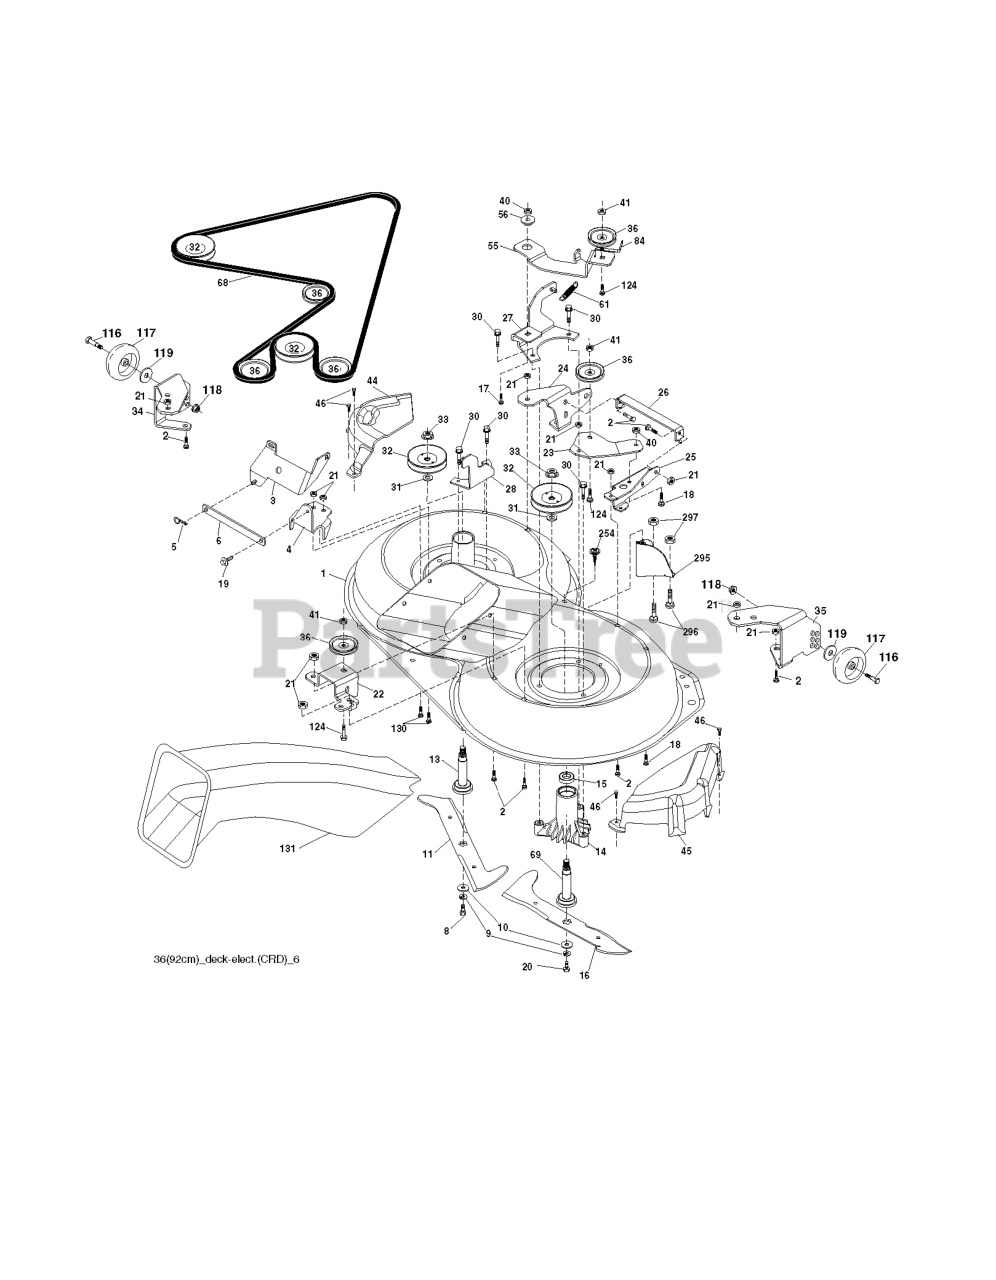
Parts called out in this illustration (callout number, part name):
2	RP BOLT 5/16-18 X3/4 ZN/YEL GR
5	RETAINER-SPRNG RB
6	BAR.SWAY.92.CRD
8	BOLT.3/8-24X1.25 GR8
9	LOCKWASHER
10	WASHER.BLADE
13	SHAFT ASM VENT
14	HOUSING.MANDREL.VENTED (MACHD)
17	BOLT.3/8-14X1.25
19	BOLT SHD 5/16-18
20	BOLT.3/8-24X1.25GR8. LHTHRD
21	LOCKNUT
26	SUPPORT
30	SCREW, WASHER HEAD
31	WASHER.SPACER.MANDREL
32	PULLEY MANDREL
33	NUT.FLANGE.LOCK.TOP
36	PULLEY.IDLER.4.25
41	NUT LOCK FLG 3/8-16 UNC
45	COVER.MANDREL.RH.CRD
46	SCREW.1/4-20X5/8
55	ARM.IDLER.92 CRD.2006
56	SPACER.RETAINER.MOWER
61	SPRING
68	BELT.DRIVE.92CM.CRD.2006
69	SHAFT.ASM.W/LWR.BRG.RH.THREAD
84	KEEPER, BELT IDLER
116	BOLT.SHOULDER.3/8-16X3-5/8.
117	RP WHEEL. GUAGE RALLY
118	NUT LOCK FLG 3/8-16 UNC
119	WASHER
124	BOLT.3/8-16X1.50
130	BOLT.CARR.SQNK.5/16-18UNC.X3/4
131	CHUTE BAGGER
254	SCREW 3/8-16X1
296	BOLT
297	NUT CENTERLOCK
